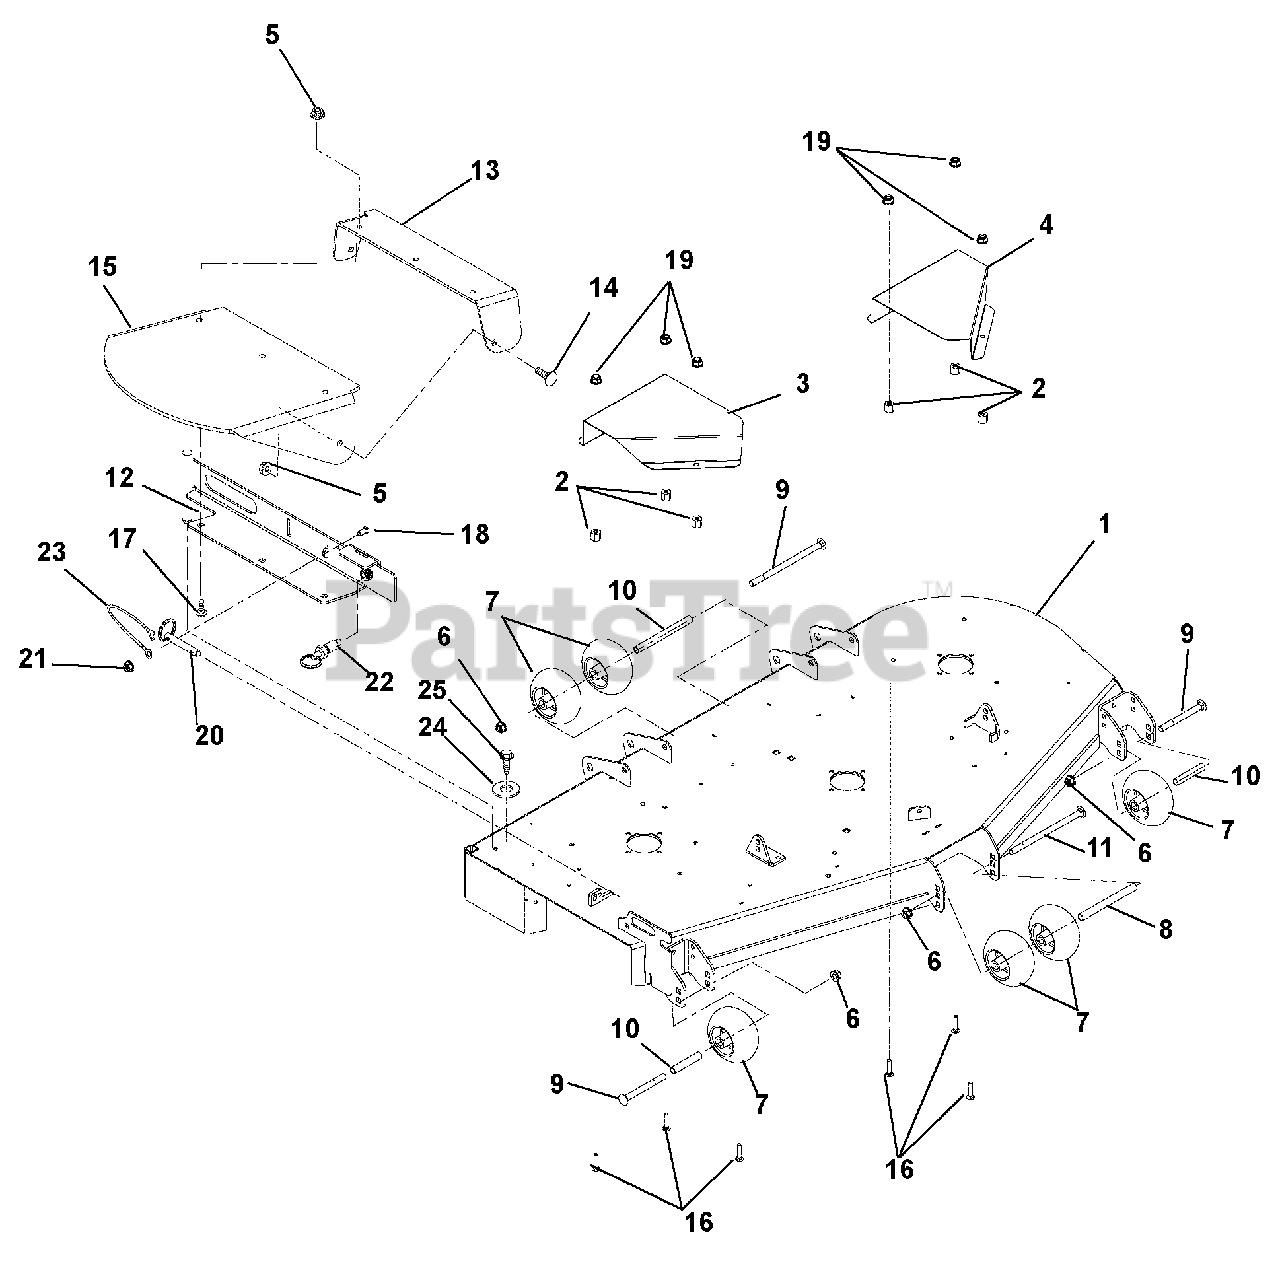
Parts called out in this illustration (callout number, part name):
1	KIT,DECK - 60" W/SAFETY DECALS
1	KIT,DECK - 52" W/SAFETY DECALS
1	KIT,DECK - 48" W/SAFETY DECALS
2	NUT-HEAVY HEX .38-16 YWZC
3	GUARD, DECK 60"-66" RH
3	GUARD, DECK 44"-52" RH
4	GUARD, DECK 60"-66" LH
4	GUARD, DECK 44"-52" LH
5	@NUT-LK-NYL-FLG .38-16 YWZC
6	@NUT-LK-NYL-FLG .50-13 YWZC
7	ANTI-SCALP WHEEL - 5X3 CTR
8	SPACER, .510X.625X6.50
9	BLT-RDHDSQNK .50-13X5.00 GR5YZ
10	SPACER, .510X.625X3.35
11	@BLT-RDHDSQNK .50-13X8.50 G5YZ
12	WLDMT, DISCHARGE CHUTE 44"-48"
12	WLDMT, DISCHARGE CHUTE 52"-60"
13	SUPPORT, CHUTE MOUNTING BRKT
14	@BLT-RDHDSQNK .38-16X1.00 G5YZ
15	CHUTE, RUBBER DISCHARGE
16	@BLT-HEX .38-16X1.25 GR5 YWZC
17	@BLT-RDHDSQNK .38-16X1.25 G5YZ
18	@BLT-HEX .25-20X.75 GR5 YWZC
19	@NUT-SPNLK-FLG .375-16 YWZC
20	PIN, SPRING BALL .375OD X 1.50
21	@NUT-LK-TOP-FLG .25-20 YWZC
22	PULL PIN,.50-13THDX.310 PLNGR
23	CABLE, 6.0 LANYARD, NYLON
24	BUMPER,RECESSED1.50X.63 W/.31
25	@SCR-TAP .31-18X.75 HWH TR YWZ
